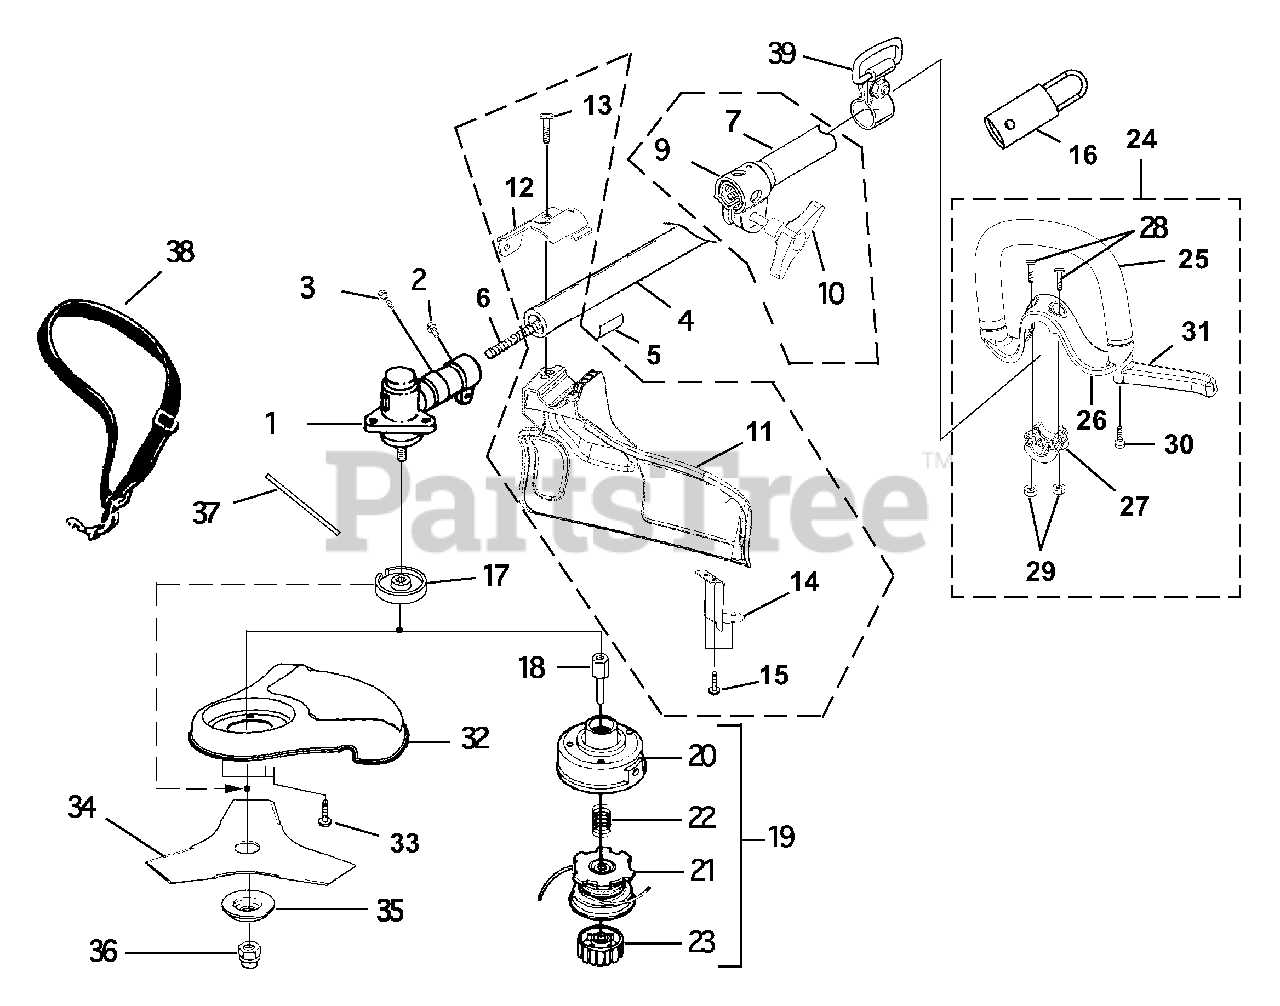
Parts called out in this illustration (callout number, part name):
1	GEAR HEAD
2	Screw, Cap Hd. (1/4-20 X 1.25")
3	Screw-Hex Hd. (10-24 x .625")
4	DRIVESHAFT HOUSING (Lower)
5	DECAL-Warning
6	SHAFT-Flexible
7	DRIVESHAFT HOUSING (Upper)
9	COUPLER KIT
11	GRASS SHIELD
12	CLAMP-Grass Shield
13	SCREW-Hex Hd. (1/4-20 x 1.25")
14	BLADE-Cut-off
15	SCREW-Pan Hd. (8-16 x 1/2")
16	END CAP
17	WASHER-Flanged
18	ADAPTER-Stringhead
19	STRINGHEAD-Complete (.095") Orange
20	HOUSING & EYELET (Dual Line)
21	SPOOL & STRING (.095") Orange
22	SPRING-Compression
23	RETAINER-Spool (L.H. Thread)
24	HANDLE w/Barrier-Complete
25	HANDLE W/Grip
26	CLAMP - "M"
27	CLAMP-Assist Handle
32	BLADE GUARD
34	BLADE-Tri-Arc™
35	WASHER-Cupped (Lower)
36	NUT-Hex (L.H.)
37	TOOL-Holding Pin
38	HARNESS
39	HANGER-Complete
